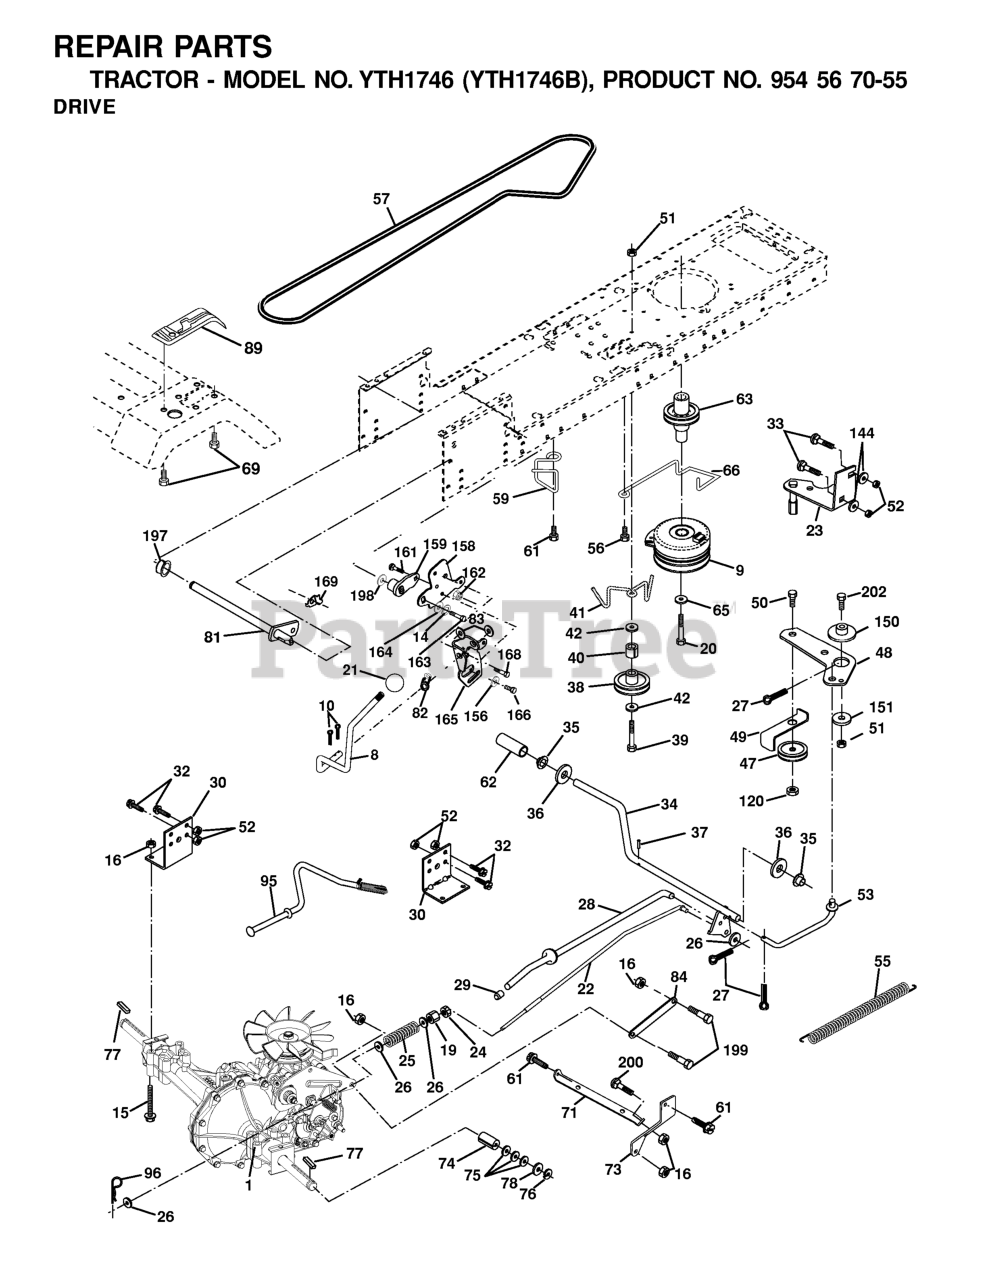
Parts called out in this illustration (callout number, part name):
8	ROD.SHIFT.FENDER.ADJ.LT.CRD
9	CLUTCH.ELECT.EVX.
10	PIN COTTER
14	LOCKWASHER
15	BOLT HEX 5/16-18 GR 5
16	NUT.71038.31-18.HEX.NYLOCK
19	NUT
20	BOLT HEX
21	KNOB.DELUXE.(PISTOL.GRIP).BLAC
22	ROD BRAKE HYDRO
24	NUT
25	SPRING ROD LT
26	WASHER
27	COTTER PIN
28	ROD, PARKING BRAKE
29	PLUNGER CAP
30	BRKT, TRNSXLE MNT 20"
32	BOLT
33	RP BOLT 5/16-18 X3/4 ZN/YEL GR
34	SHAFT, FOOT PEDAL
35	BEARING.NYLON
37	DRIVE PIN
38	PULLEY.FLAT
39	BOLT
40	SPACER, SPLIT
41	KEEPER, BELT IDLER
42	WASHER
47	IDLER PULLEY
48	BELLCRANK, CLUTCH
49	RETAIN BELT
50	BOLT
52	LOCKNUT
53	LINK, CLUTCH LT
55	SPRING, RETURN LT
56	SCREW THDROL 3/8-16 X 1-1/2
57	DRIVE BELT, LTH & YTH TRACTORS
59	KEEPER, BELT CENTER
61	SCREW 3/8-16X3/4
62	PEDAL COVER T
63	PULLEY, ENGINE
65	LOCKWASHER
66	KEEPER BELT ENGINE
69	SCREW.HI-LO.CONSOLE
71	STRAP TORQUE LH HYDRO
73	STRAP TORQUE RH HYDRO
74	SPACER AXLE
77	SQUARE KEY
81	SHAFT ASM CROSS TAPERED
82	SPRING,TORSION
83	WASHER
84	LINK TRANSAXLE
89	CONSOLE, SHIFT
95	CONTROL ASM. BYPASS HYDRO
96	RETAINER M
120	NUT LOCK FLG 3/8-16 UNC
144	Washer 11/32 x 5/8 x 16 Ga SD
150	SPACER, RETAINER
151	WASHER 12/32X2X10GA
156	WASHER.SRRTD.5/16
158	BRACKET
159	HUB
161	BOLT
162	NUT.CROWNLOCK.1/4
164	Washer 5/8 x .281 x 10 Ga.
165	RP BRACKET
168	BOLT.SHOULDER.5/16-18X
169	PLATE.FASTENING.CROSS.SHAFT
197	NYLINER SNAP 5/8" ID
198	WASHER.NYL.7/8IDX.105"HYD CR
199	BOLT SHOULDER 5/16-18 UNC
